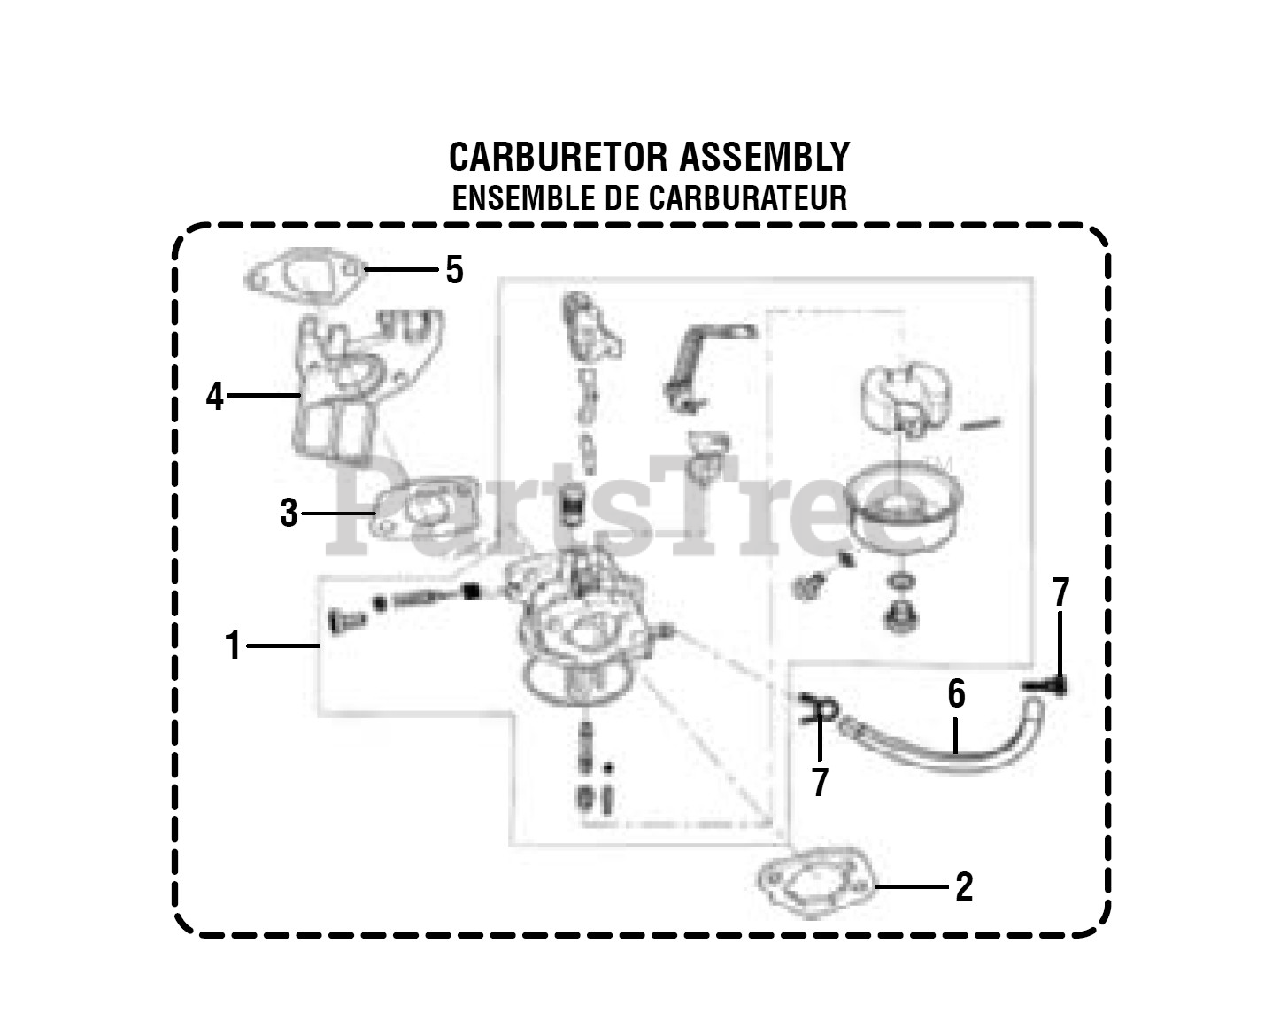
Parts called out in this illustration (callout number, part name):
1	Carburetor Assembly
2	Air Cleaner Gasket
3	Carburetor Gasket
4	Carburetor Insulator Plate
5	Carburetor Insulator Gasket
7	Clamp
